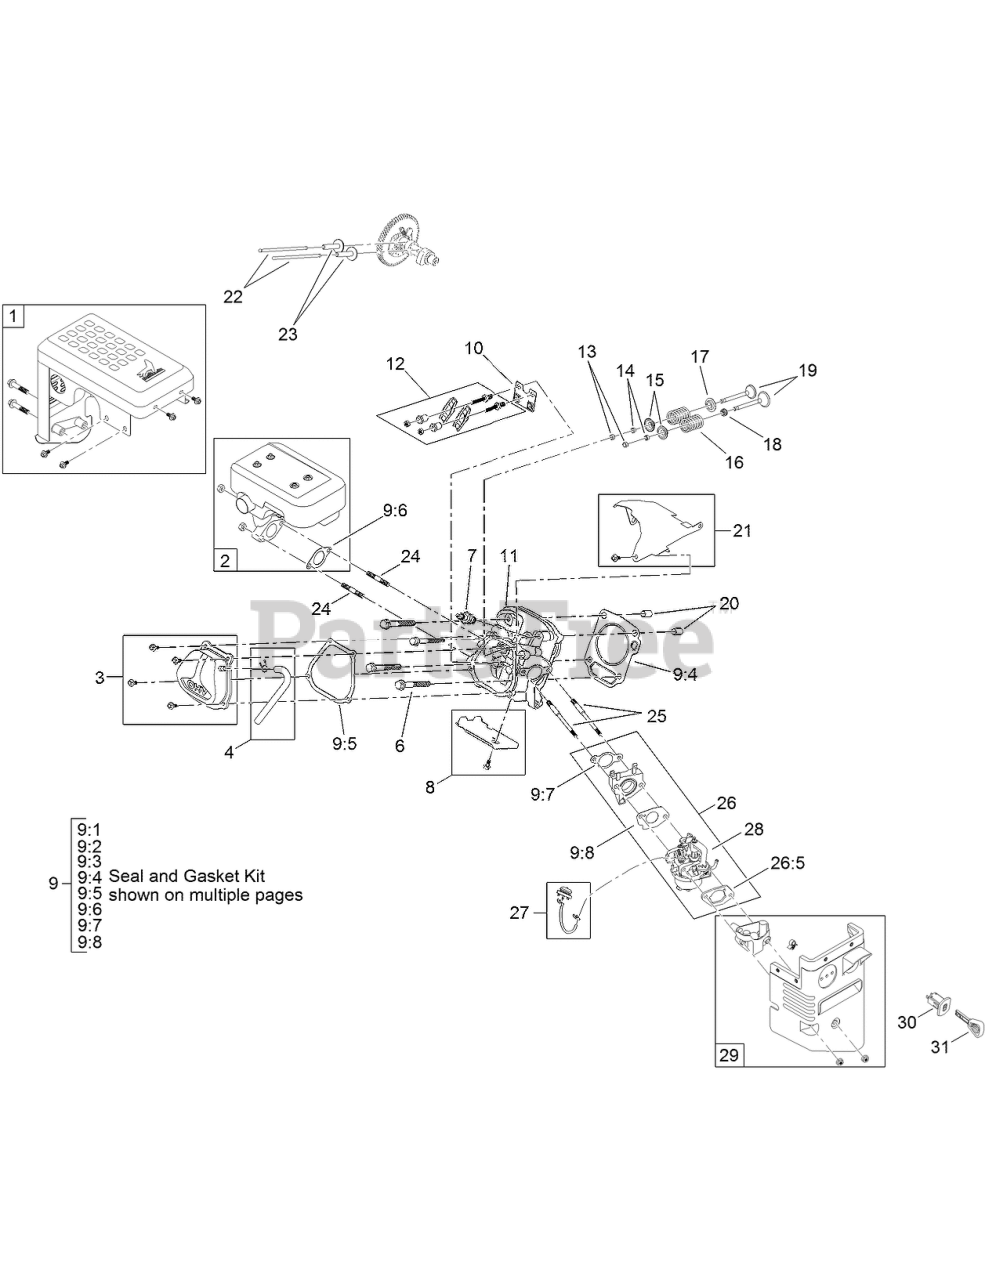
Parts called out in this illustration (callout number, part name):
1	MUFFLER SHIELD KIT
2	MUFFLER KIT
3	VALVE COVER KIT
4	BREATHER TUBE KIT
6	SCREW-HHF
7	PLUG-SPARK
8	LOWER HEAT SHROUD KIT
9	SEAL AND GASKET KIT
9:1	Seal-Oil
9:2	Seal-Oil
9:3	GASKET-COVER, CRANKCASE
9:4	GASKET-HEAD, CYLINDER
9:5	GASKET-COVER, VALVE
9:6	Gasket-Exhaust
9:7	GASKET-CARBURETOR
9:8	GASKET-CARBURETOR
10	PLATE-GUIDE, PUSH ROD
11	HEAD-CYLINDER
12	ROCKER ARM ASM
13	ROTATOR-VALVE
14	KEEPER-VALVE
15	RETAINER-SPRING, VALVE
16	SPRING-VALVE
17	SEAT-SPRING, VALVE
18	SEAL-STEM, VALVE
19	VALVE KIT
20	PIN-DOWEL
21	UPPER HEAT SHROUD KIT
22	ROD-PUSH
23	LIFTER-VALVE
24	STUD-MOUNT, MUFFLER
25	STUD-MOUNT, CARBURETOR
26	COMPLETE CARB SERVICE KIT
26:5	GASKET-COATED, RUBBER
27	PRIMER KIT
28	CARB REPAIR KIT WITH GASKETS
29	HEATER BOX KIT
30	SWITCH-KEY
